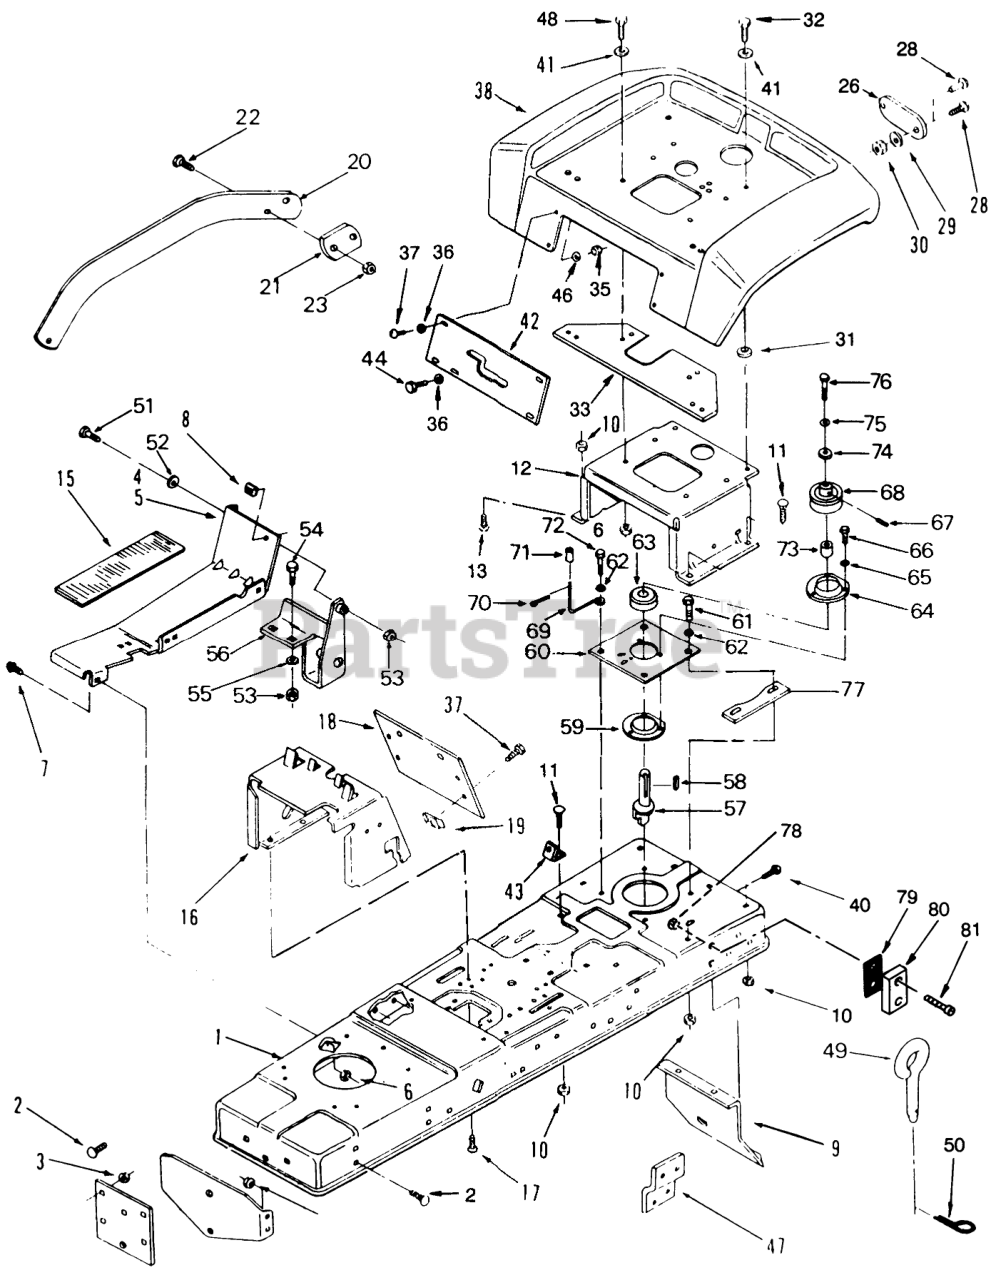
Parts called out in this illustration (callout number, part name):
1	FRAME-B CHASSIS R
2	Bolt
3	NUT-LOCK, NI
4	RH FOOTREST R
5	Footrest LH
6	NUT-LOCK, NI
7	BOLT-CARR
8	BUMPER
9	Hitch-Drawbar
10	NUT-LOCK, NI
11	BOLT-CARR
12	SUPPORT-SEAT R
13	BOLT-CARR
15	MAT-FOOTREST R.H.
16	ASS'Y-HOODSTAND B
17	SCREW
18	PLATE-HOODSTAND R B
20	BAR-PIVOT R
21	SPACER R
22	SCREW-HH
23	NUT-LOCK, NI
26	Reflector
28	Poprivet
29	Lockwasher
30	Nut
31	WASHER
32	Bolt
33	PLATE-SEAT R
35	Nut
36	WASHER-FLAT
37	Screw
38	FENDER R
40	SCREW-HH
41	WASHER-PLAIN
42	PLATE-SHIFT R
43	BRACKET FENDER
44	Bolt
46	WASHER-LOCK
47	BRKT SWITCH BRAKE R
48	BOLT-CARR
49	PIN-TOOL
50	Hairpin Cotter
51	SCREW-HH
52	WASHER-SPECIAL
53	NUT-LOCK, NI
54	BOLT-CARR
55	WASHER-PLAIN
56	ASS'Y-BRACKET R.H R
57	SHAFT-DRIVE
58	KEY
59	BEARING-CUP W/NUTS
60	PLATE-MTG R
61	SCREW-HH
62	WASHER-PLAIN
63	BEARING-BALL
64	BEARING-CUP
65	WASHER-LOCK
66	SCREW-HH
67	SCREW-SQH
68	PULLEY
69	GUIDE-BELT
70	PIN-COTTER
71	SPACER
72	SCREW-HH
73	SPACER SHAFT
74	WASHER
75	WASHER-LOCK
76	SCREW-HH
77	SPACER-MTG PLATE R
78	Nut
79	SPACER-RUB BLOCK R
80	Block Rubber
81	PHCRS 1/4-20 X 1
